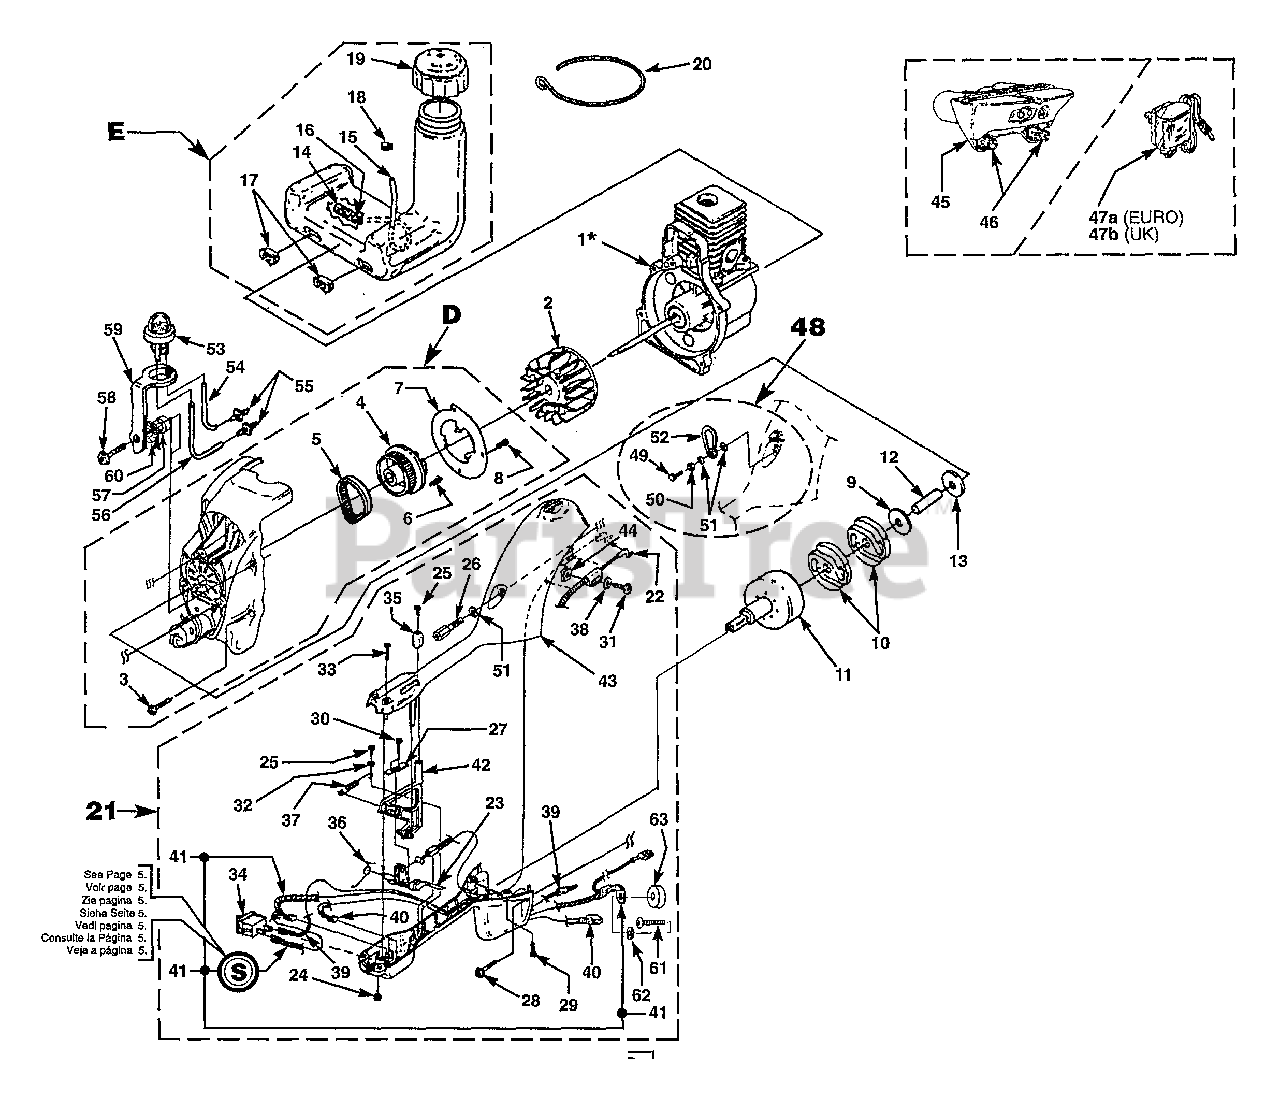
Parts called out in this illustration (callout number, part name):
1	SHORT BLOCK
2	ROTOR w/Starter Pawls
3	SCREW-Thread Form. (10-24 X 3/4")
4	PULLEY-Starter
5	BELT-Starter
6	SCREW- Thread Forming (8-32 X 1")
8	SCREW-Plastite (8-16 5/8")
9	WASHER-Flat
11	CONNECTOR & DRUM
12	SPACER
14	FILTER-Fuel
15	TUBING-Rubber (5")
16	CLAMP-Wire
17	BUMPER-Rubber
18	FITTING-In Line Fuel
19	FUEL CAP
20	SUPPORT WIRE
21	CLUTCH HOUSING 3 CONTROL HANDLE
22	CABLE-Throttle
23	TRIGGER
24	NUT-Hex (10-24)
25	SCREW-Thread Forming (#4-20 X 1/4")
26	SCREW-Adaptor
27	RETAINER
28	SCREW-Torx Truss Hd. (#10-24 X 1 1/4")
29	SCREW-Thread Forming (#10-14 X 1/2")
30	SCREW-Thread Forming (16-20 X 1/2")
31	SCREW-Socket Head
33	SCREW-Truss Hd. (#10-24 X 1 7/8")
34	SWITCH-Rocker
35	KNOB-Starter Lever
36	SPRING-Torsion
37	SPRING-Extension
38	WASHER-Flat
39	LEAD-Electrical
40	LEAD-Electrical
41	LEAD-Electrical
42	STARTER LEVER w/BAR
43	CLUTCH HOUSING
44	NUT-Tinnerman
45	BATTERY PACK
46	KNOB-Battery Pack
47A	CHARGER-Battery Pack (EURO)
47B	CHARGER-Battery Pack (UK)
48	HANGER KIT
50	WASHER-Lock
53	BUTTON-Start Assist
54	LINE-Fuel (2.0") (5,0cm)
55	FITTING-Fuel Line
56	LINE-Fuel (2.5") (6,5cm)
57	SPACER
58	SCREW- (10-24 x 1.00")
59	BRACKET
60	WASHER-External Lock
61	BATTERY POST
D	COMPLETE STARTER ASSEMBLY
E	FUEL TANK COMPLETE
